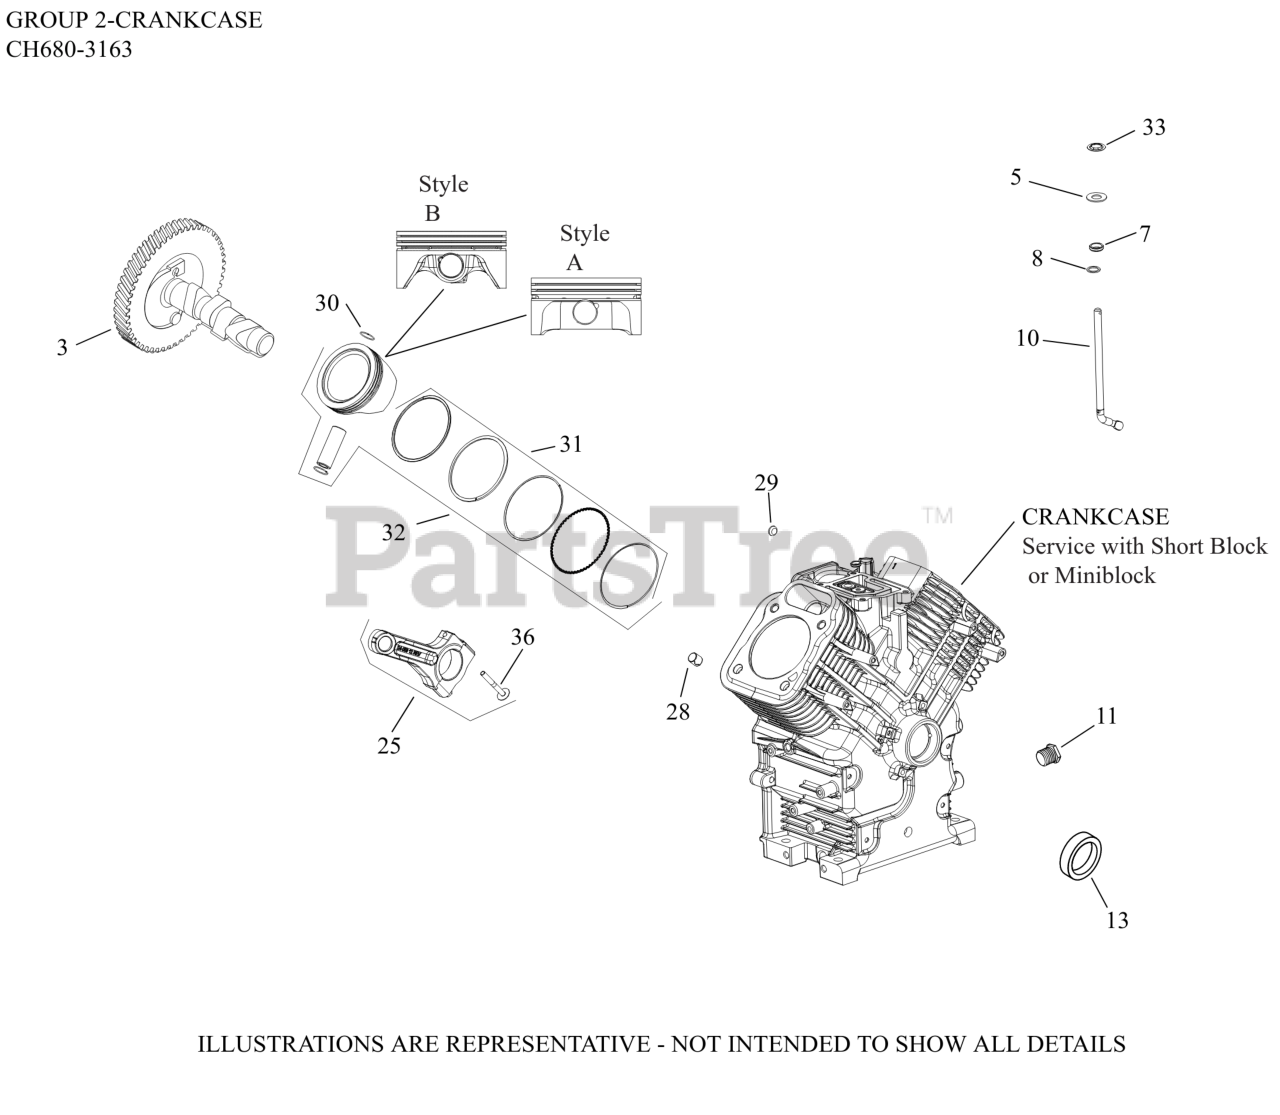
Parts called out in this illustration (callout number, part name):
3	KIT, CAMSHAFT
5	WASHER, FLAT 9 MM
7	SEAL, GOVERNOR CROSS SHAFT
8	WASHER, FLAT 11/32"
10	SHAFT, GOVERNOR CROSS
13	SEAL, OIL (HELIX LIP)
25	ROD, ASSEMBLY CONNECTING
28	PIN, LOCATING
29	PLUG, CUP
30	RETAINER, PISTON PIN
31	RING SET (STD) STYLE B
31	RING SET (.08) STYLE B
31	RING SET (.25) STYLE B
31	RING SET (.50) STYLE B
32	KIT, PISTON (STD) STYLE B
32	KIT, PISTON (.08) STYLE B-(#DSC)
32	KIT, PISTON (.25) STYLE B
32	KIT, PISTON (.50) STYLE B
33	RETAINER, RING
36	KIT, ROD BOLTS-(#25086677S)
49	PLUG, SQ HD PIPE 3/8"
